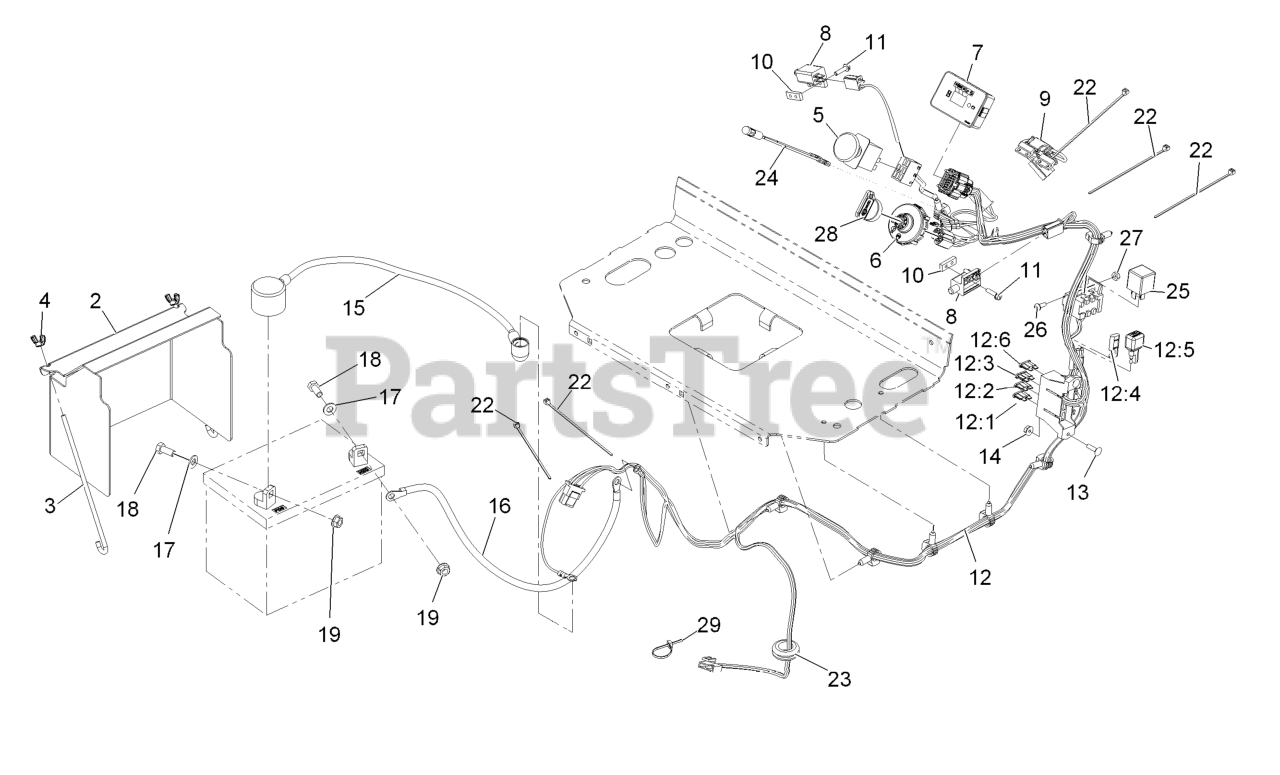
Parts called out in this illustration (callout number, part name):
2	COVER-BATTERY
3	BOLT-HOLDDOWN
4	WINGNUT
5	SWITCH-PTO, ON-ON
8	SWITCH-CLOSED, NORMALLY
9	HARNESS-SWITCH, REED
10	PLATE-TAPPED
11	SCREW-HWH
12:1	FUSE-BLADE, 30 AMP
12:2	FUSE-BLADE, 25 AMP
12:3	FUSE-BLADE, 10 AMP
12:4	CAP-PLUG
12:6	FUSE-BLADE, 15 AMP
13	SCREW-CARR
15	CABLE-BATTERY, POSITIVE
16	CABLE-BATTERY, BLACK
17	WASHER-PLAIN
18	SCREW-HH
19	NUT-HHF, SMOOTH
22	TIE-CABLE
23	GROMMET
24	INDICATOR-LED, RED
26	SCREW-PPH
27	NUT-LOCK, NI
28	KEY-IGNITION
29	TIE-CABLE
